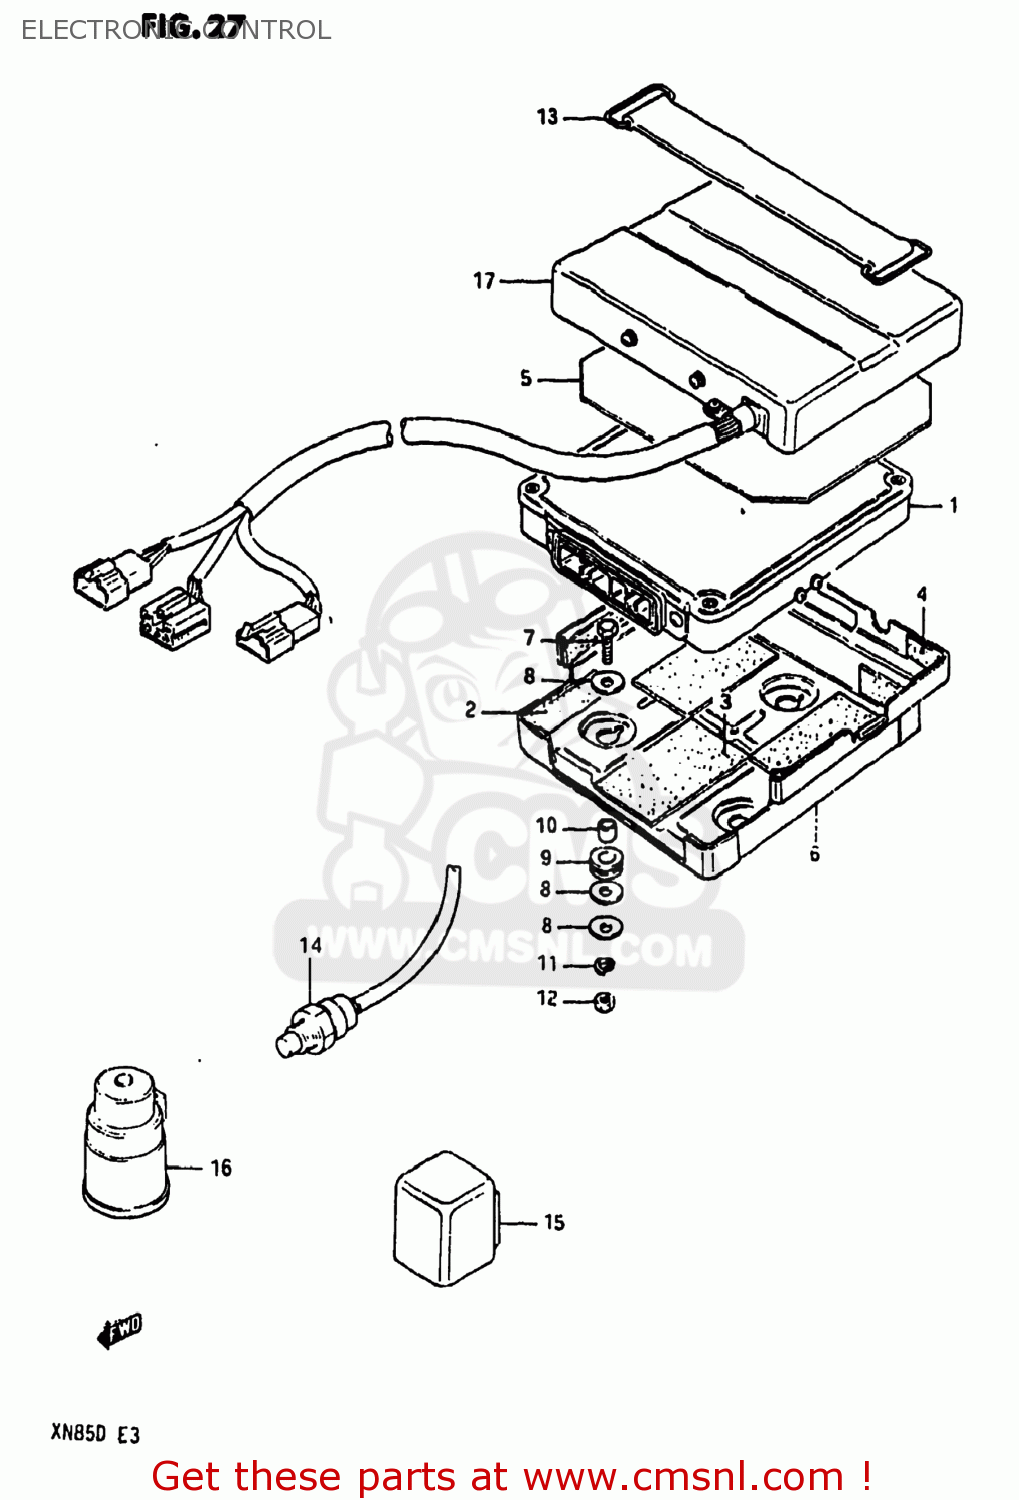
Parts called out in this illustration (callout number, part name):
1	ELECTRONIC CONTROL UNIT
2	PROTECTOR,20X9
3	CUSHION, NO. 2
4	CUSHION, NO. 3
5	CUSHION, NO. 5
6	HOLDER,CONTROL UNIT
7	BOLT
8	WASHER
9	CUSHION
10	SPACER(6.1X9X7.5)
11	LOCK WASHER
12	NUT
13	BAND
14	SENSOR,OVER HEAT WARNING
15	SENSOR,IDLE POSITION
16	CIRCUIT,OPENING RELAY
17	CDI UNIT
